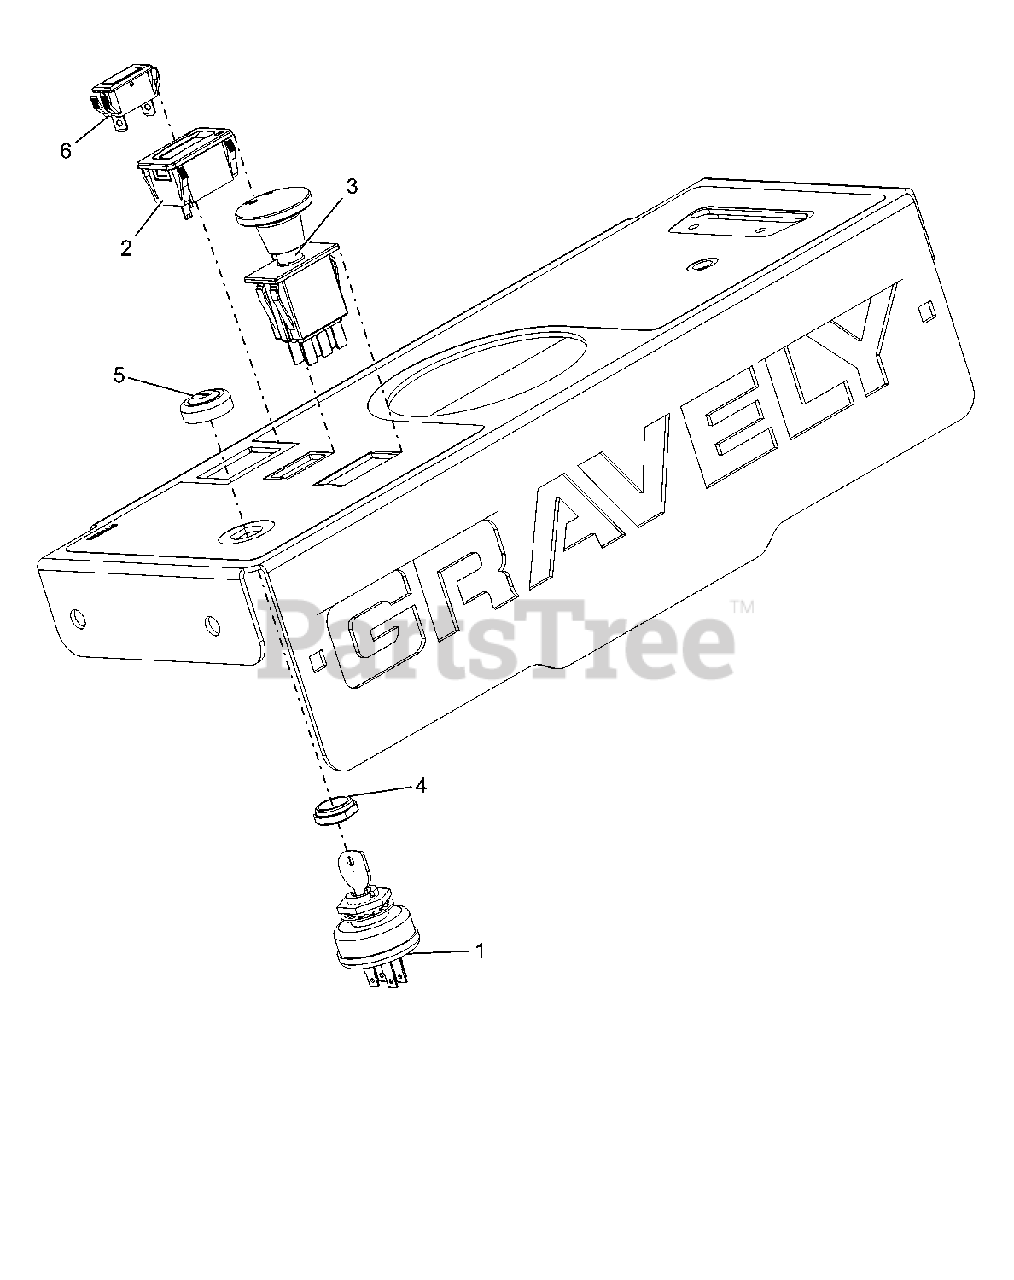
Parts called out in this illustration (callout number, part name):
1	SWITCH, KEY - 3 POSITION
2	METER, HOUR SMART SENSE W/O SV
3	SWITCH, CLUTCH (WITH GRAPHIC)
4	NUT-PANEL .625-32 GRECO REV
5	CAP, IGNITION SWITCH
6	LIGHT, INDICATOR
